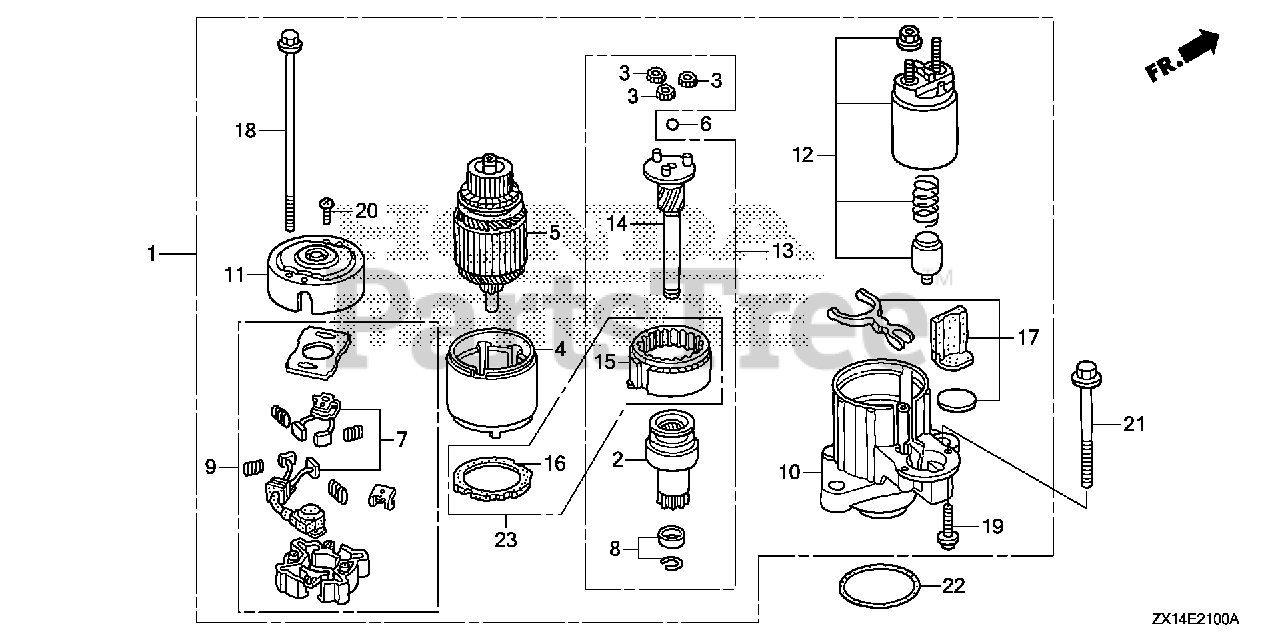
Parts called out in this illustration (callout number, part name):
1	STARTER MOTOR ASSY.
2	CLUTCH, OVERRUNNING
3	GEAR ASSY., PLANETARY
6	BALL, STEEL
7	BRUSH SET
8	STOPPER SET, SLEEVE
9	HOLDER, BRUSH
10	BRACKET, FR.
11	BRACKET, RR.
12	SWITCH ASSY., MAGNET
13	SHAFT ASSY., CLUTCH
14	SHAFT ASSY., GEAR
15	GEAR ASSY. (INNER)
16	GASKET
18	BOLT A, THROUGH
19	SCREW, PAN (6X22)
19	SCREW, PAN (6X22) (SPECIAL)
20	SCREW, PAN (5X8)
21	BOLT, FLANGE (10X90)
22	O-RING (59.4X3.1)
23	GEAR ASSY. (INNER)
